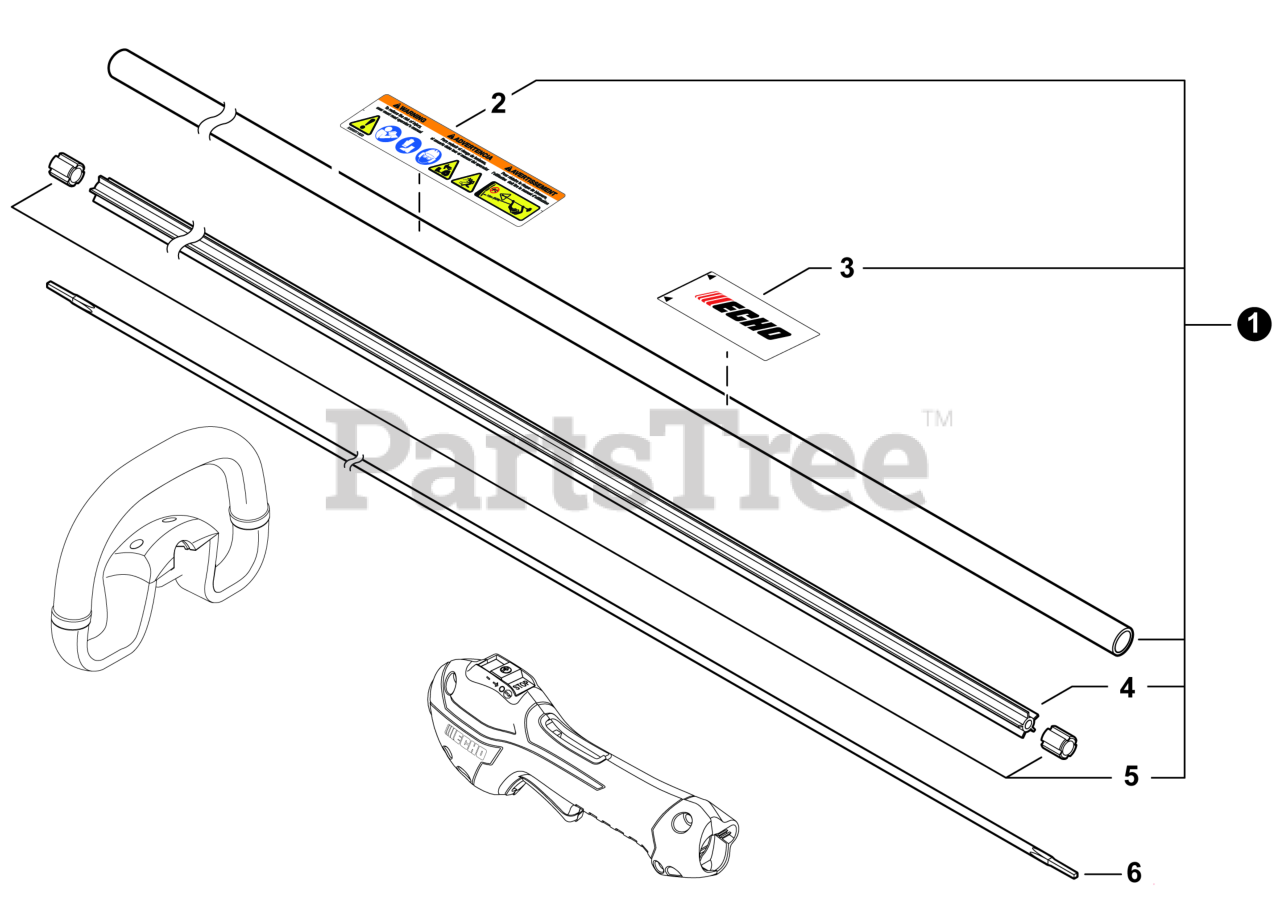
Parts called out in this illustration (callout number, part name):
1	MAIN PIPE ASSY
2	LABEL - CAUTION ISO
3	LABEL - HANDLE LOCATION
4	LINER, FLEXIBLE
5	STOPPER
6	DRIVESHAFT - FLEXIBLE
